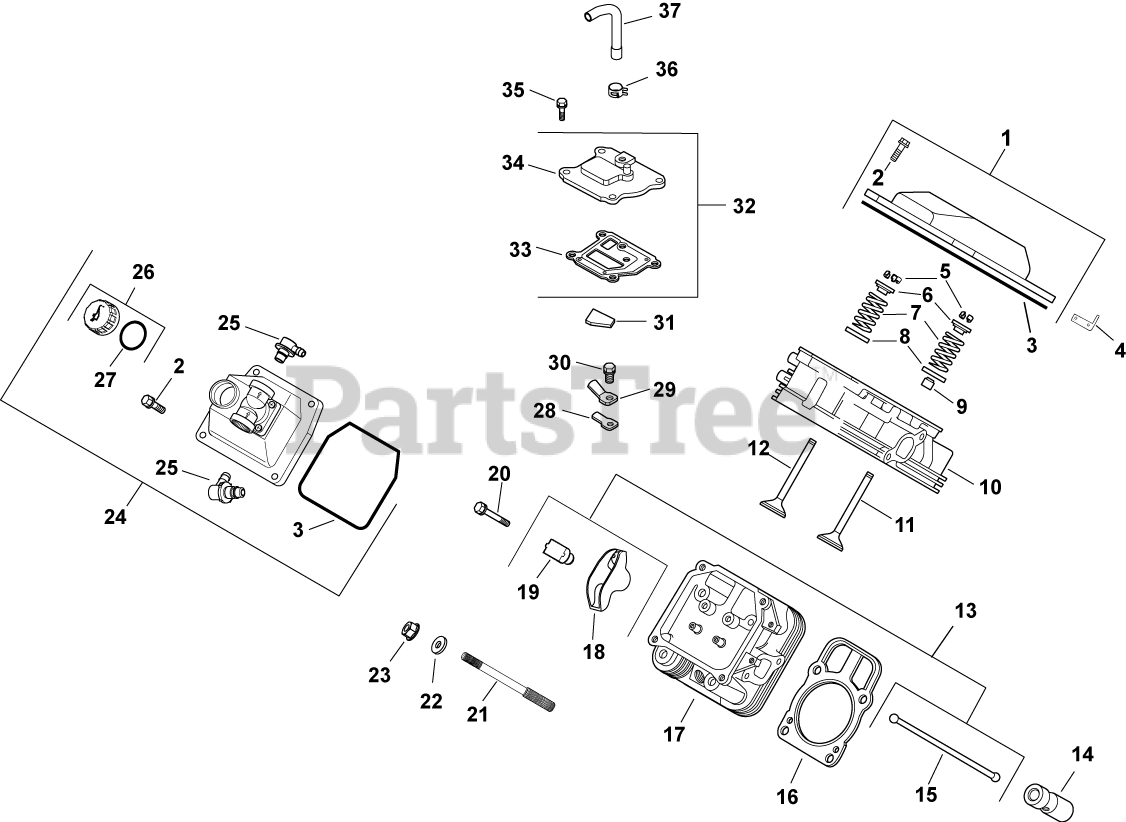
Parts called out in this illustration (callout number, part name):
1	KIT, VALVE COVER-PLAIN
2	SCREW, FLG M6X1.0X30
3	O-RING (YELLOW) -USE 24 153 30-S
4	STRAP, LIFTING-USE 25 445 03-S
5	KIT, RETAINER
6	RETAINER, VALVE SPRING - USE 25 173 28-S
7	SPRING, VALVE
8	RETAINER, SPRING
9	SEAL, VALVE STEM - (#2503214S)
10	HEAD, SERVICE ASSY CYL #1-USE 24 318 106
11	VALVE, INTAKE (STD)
12	VALVE, EXHAUST (STD) - USE 32 016 01-S
13	KIT, VALVE TRAIN
14	LIFTER, HYDRAULIC VALVE-USE 25 351 10-S
15	ROD, PUSH
16	CYL HEAD GASKET KIT-USE 24 841 04-S
17	HEAD, SERVICE ASSY CYL #2-USE 24 318 114
18	ARM, ROCKER
19	PIVOT, ROCKER ARM
20	SCREW, FLG M6X1.0X34
21	STUD, M8X1.25
22	WASHER, FLAT 8.6 MM
23	NUT, FLG M8X1.25
24	KIT, VALVE COVER-FUEL PUMP
25	KIT, 90 DEG. FITTING
26	CAP ASSY, OIL FILL (YELLOW)
27	O-RING-USE 24 153 32-S
28	REED, BREATHER
29	RETAINER, REED
30	SCREW, FLG THD FRM M5X.8X10
31	FILTER, BREATHER-USE 24 050 11-S
32	KIT, BREATHER ASSEMBLY
33	GASKET, BREATHER-USE 24 041 67-S
34	COVER, BREATHER -USE 24 033 01-S
35	SCREW,FLG THD FRM M6X1.0X20-(#25086396S)
36	CLAMP, HOSE (KM)-USE 25 237 31-S
37	HOSE, BREATHER
2401602-S	VALVE, EXHAUST (.25)
2401702-S	VALVE, INTAKE (.25)
24755147-S	KIT, CYLINDER HEAD HARDWARE
